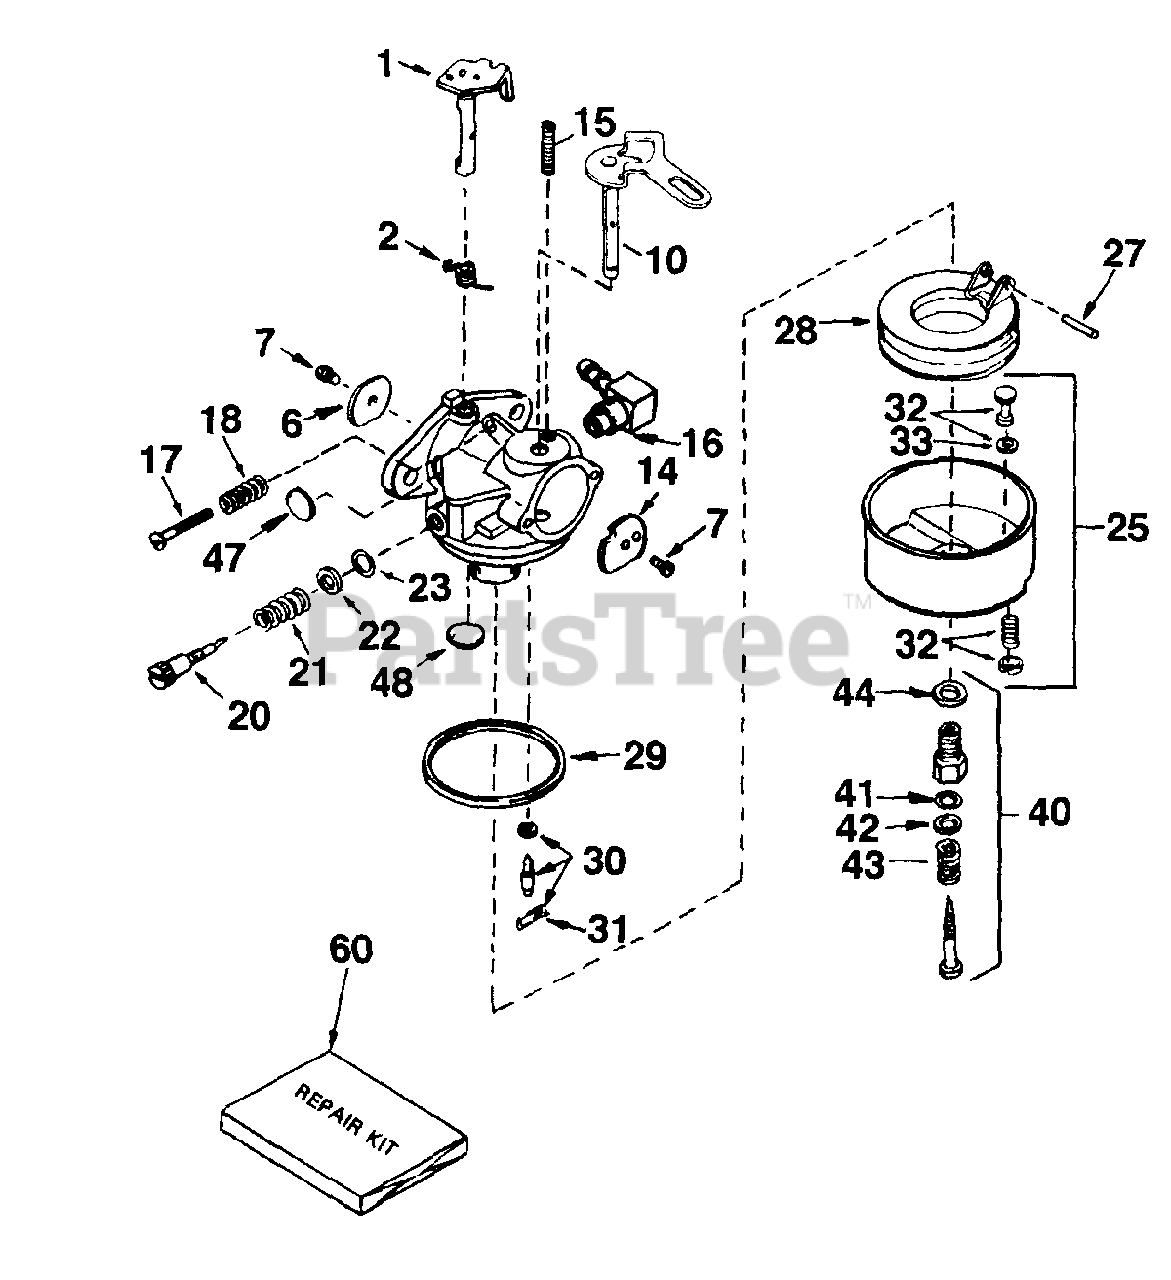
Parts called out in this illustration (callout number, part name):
1	Throttle Shaft & Lever Ass'y.
2	Throttle Return Spring
6	Throttle Shutter
7	Throttle & Choke Shutter Screw
10	Choke Shaft & Lever Ass'y.
14	Choke Shutter
15	Choke Positioning Spring
16	Fuel Fitting
17	Idle Speed Screw
18	Tension Spring
20	Idle Mixture Screw
21	Idle Tension Spring
22	Washer, Idle Screw
23	O-Ring, Idle Screw
25	Float Bowl Ass'y.
27	Shaft, Float
28	Float
29	O-Ring, Float Bowl to Body
30	Inlet Needle, Seat & Clip
31	Spring Clip
32	Bowl Drain Ass'y.
33	Drain Plunger Gasket
40	Main Adj. Screw Ass'y.
41	O-Ring, High Speed Mixture Screw
42	Washer, High Speed Mixture Screw
43	Tension Spring, High Speed Mixture Screw
44	Bowl Nut Washer
47	Welch Plug, Idle Mixture Well
48	Welch Plug, Atmospheric Vent
60	Repair Kit
